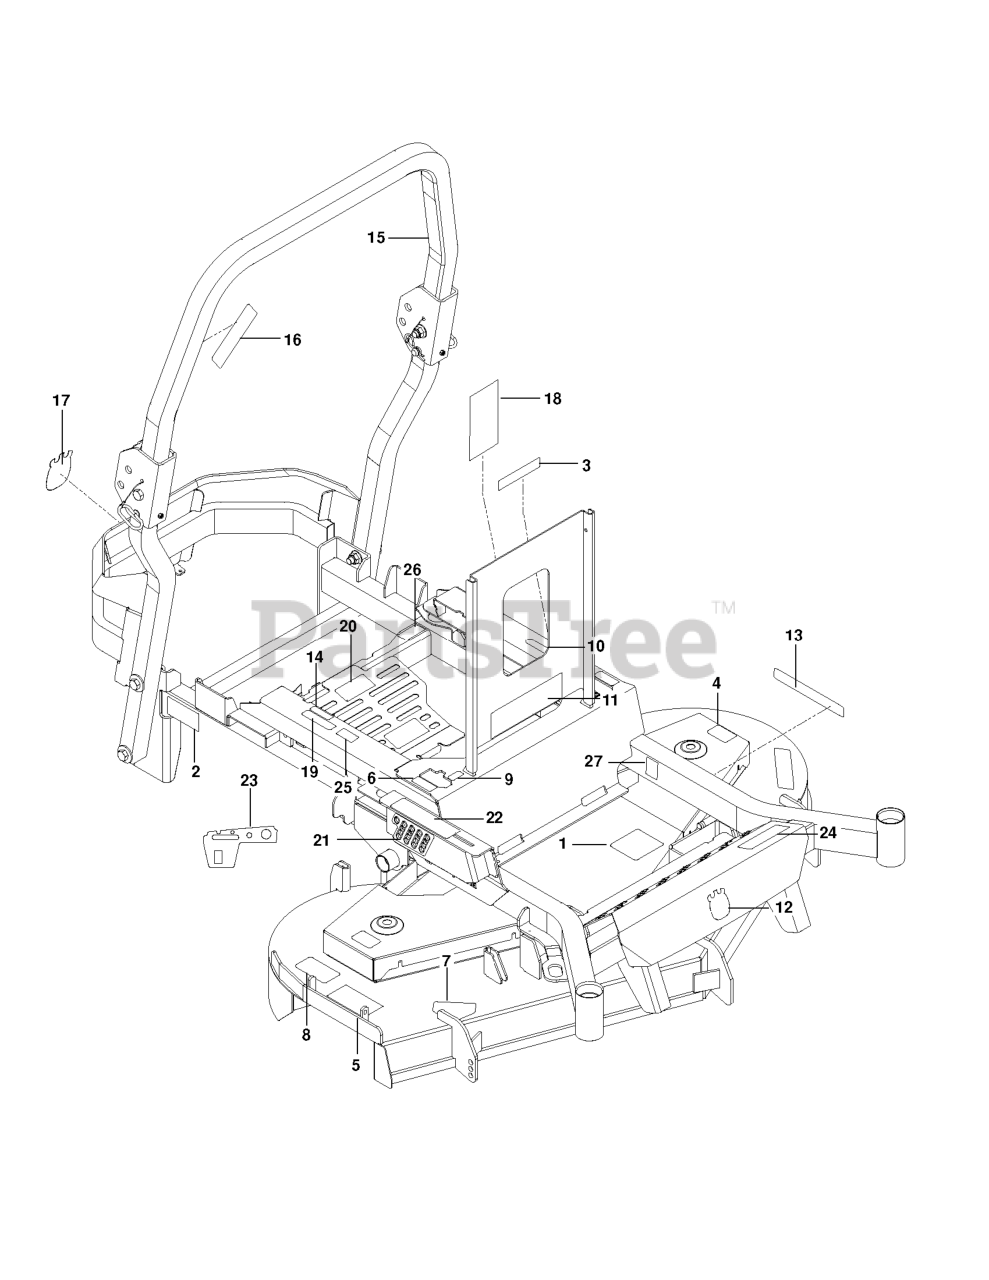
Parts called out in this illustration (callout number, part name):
1	DECAL, BELT ROUTING
2	DECAL, BELT DRIVE
3	EURO DECAL-BATTERY WARNIN6
4	DECAL.DECK.6MIL.EURO.NOSTEP
5	DECAL, EURO SEVERING
6	DECAL, MOTION CONTROL
7	DECAL, CPSC
8	DECAL.DECK.6MIL./DEF.SHLD.WARN
9	DECAL, F.S.T.
10	DECAL, PARK BRAKE
11	DECAL, WARNING
12	DECAL.AUGER.HUSQ.CROWN.SNOW
13	RP.DECAL.BADGE.170MM.TEXTLOGO
14	DECAL, FUSE
15	DECAL, ROPS
16	DECAL, ROPS, WARNING
17	DECAL, CROWN H, 110MM
18	DECAL, SERVICE
19	DECAL, WARNING SPARK ARRESTOR
20	HG_DECAL, ZT-3400
21	DECAL, HEIGHT
22	DECAL, RELEASE LEVER
23	DECAL, CONTROL, GAS
24	DECAL.P-ZT.54
25	DECAL, ECM, AUSTRALIA
26	DECAL, FUEL
27	DECAL.80.DBA.AUSTRALIA
